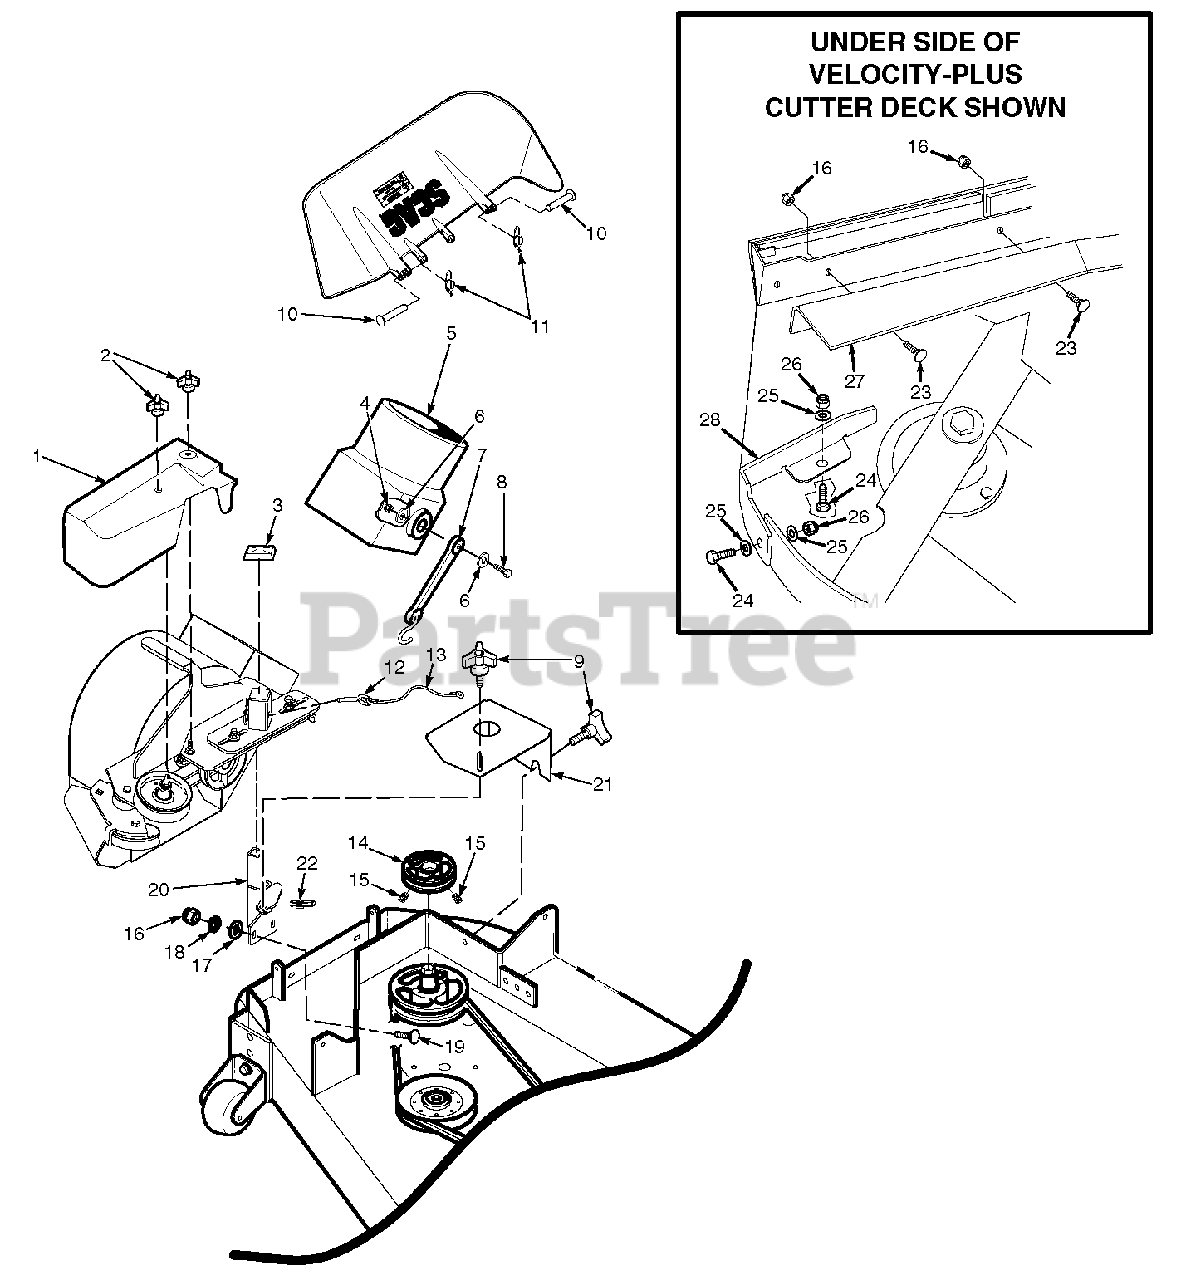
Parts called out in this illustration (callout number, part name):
1	Belt Cover, GC-STC
2	Wingnut, Plastic 3/8" Small
3	Cap, Square Vinyl
4	Nut, Elastic Stop 1/4-20
5	Adapter, Blower GC-STC,
6	Flatwasher, 1/4-.312 x .750 x .065
7	Rubber Strap 7-3/4"
8	Bolt, Hex Head 1/4-20 x 1-1/4"
9	Knob W/Stud, 3/8-16 x 1-1/4"
10	Clevis Pin, 5/16 x 1-1/2"
11	Pin, Rue Cotter 5/16 Dia.
12	Pin, Ring 1/2 x 2-1/4"
13	Lanyard
14	Pulley, 4.0" Dia. 1.125 Bore
15	Setscrew, 5/16-18 x 3/8"
16	Nut, Elastic Stop 3/8-16
17	Lockwasher, 3/8"
18	Flatwasher, 3/8-.391 x .938 x .105
19	Bolt, Carr. 3/8-16 x 1-1/4" Grade 5
20	Mounting Post Weldment, Blower
21	Belt Cover Assembly, GC-STC-48V w/Cap
21	Belt Cover Assembly, GC-STC-52V w/Cap
23	Bolt, Carriage 3/8-16 x 1"
24	Bolt, Hex Head 5/16-18 x 1"
25	Flatwasher, 5/16-.375 x .875 x .083
26	Nut, Elastic Stop 5/16-18
27	Baffle, Front 48" Deck
27	Baffle, Front 52" Deck
28	Baffle, Turbo 48" Deck
28	Baffle, Turbo 52" Deck
